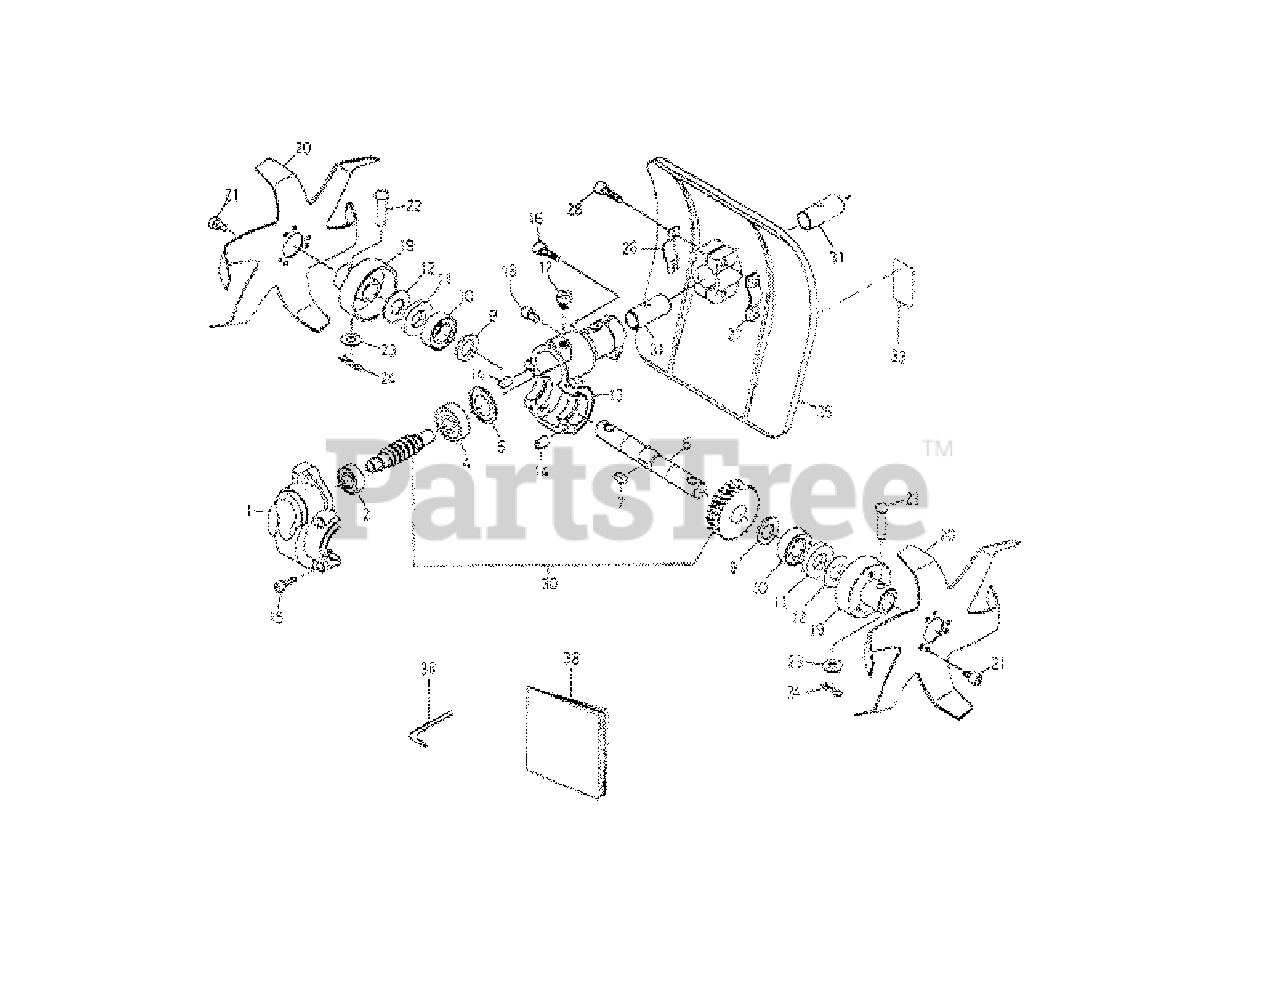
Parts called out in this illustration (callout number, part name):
2	Ball Bearing 6001zz
4	Ball Bearing 6301zz
10	Ball Bearing 6003zz
15	Bolt, M5X25mm
16	Bolt, M6X18mm
18	Bolt M5X10mm
19	Holder, Rotor
30	Gear Assembly
33	Caution Plate
36	Wrench, Torx
38	Instruction Book
